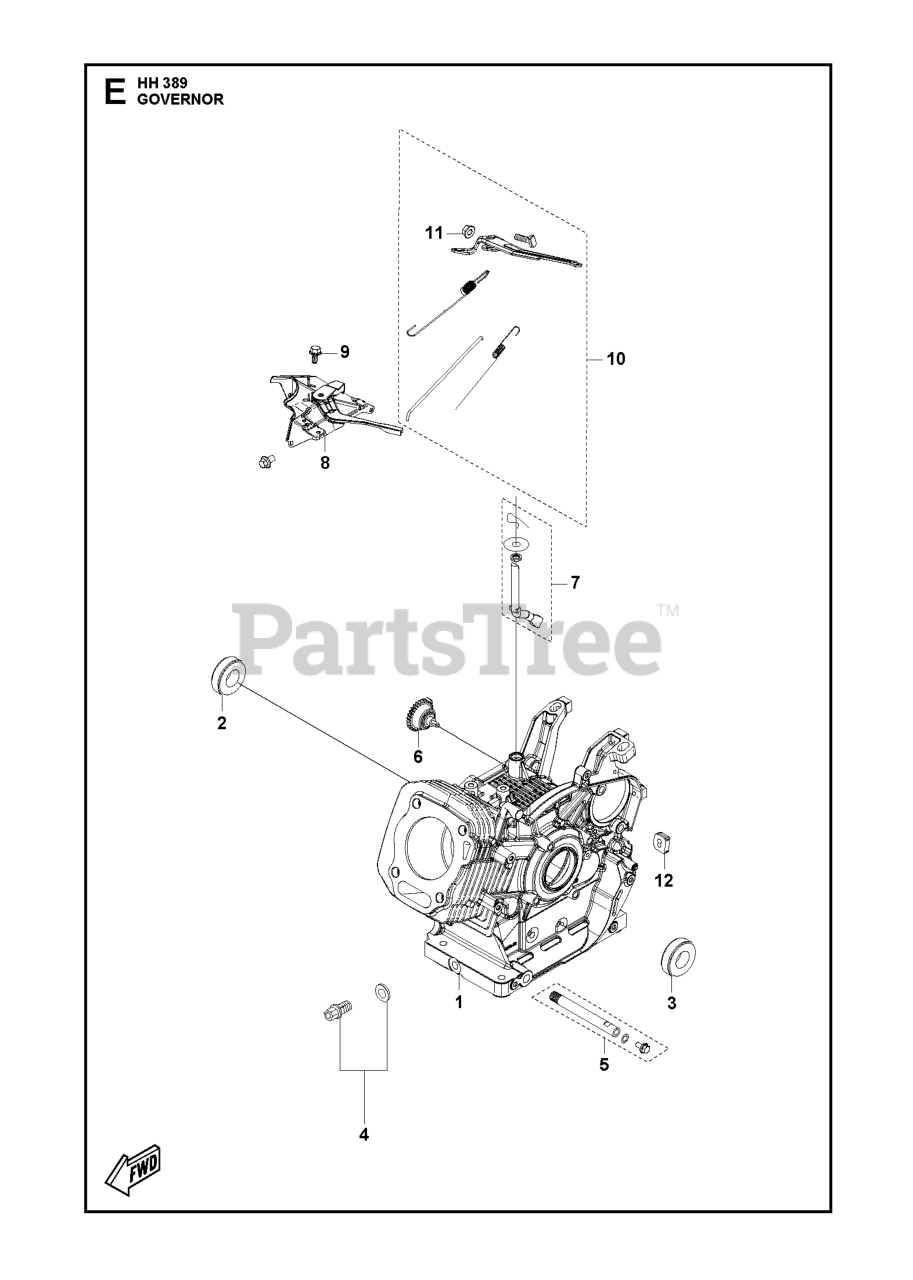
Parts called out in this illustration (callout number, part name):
2	SEAL OIL SEAL
3	SEAL OIL SEAL
6	GEAR GOVERNOR GEAR
7	ARM SPEED REGULATING ARM KIT
8	THROTTLE HANDLE
9	BOLT
10	THROTTLE ASSY
11	NUT
12	PLUG RUBBER PLUG
